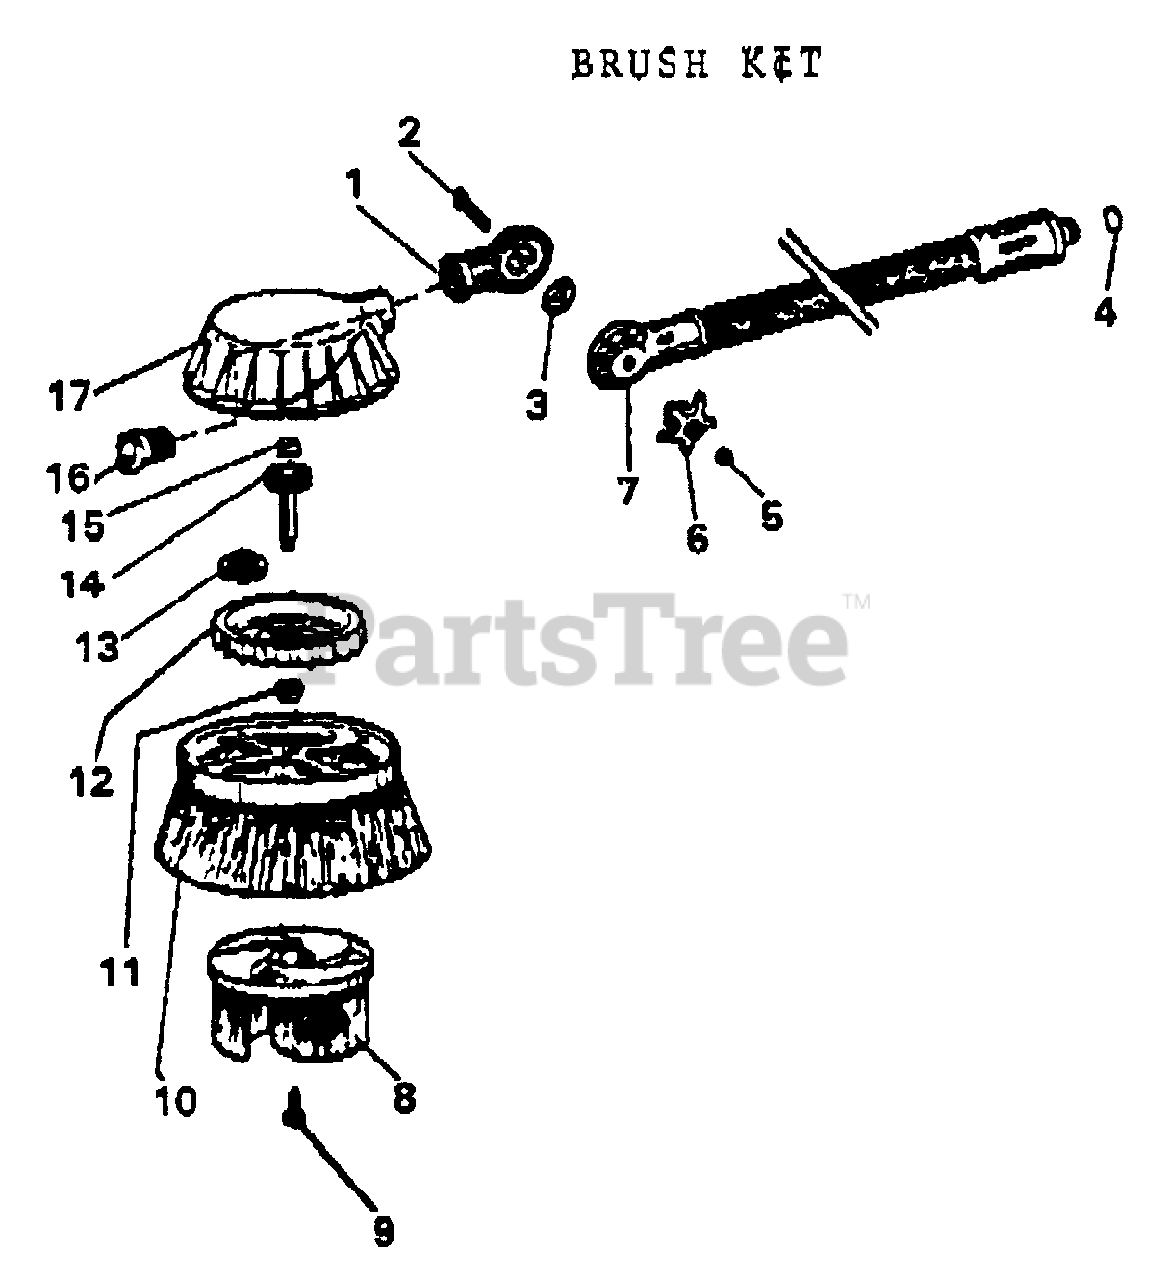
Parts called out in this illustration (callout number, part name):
1	CONNECTOR, ADJUSTABLE
2	SCREW M6×40
3	GASKET, CONNECTOR
4	O-RING
5	NUT - 6
6	KNOB, REGULATING
7	HAND GRIP, BRUSH
8	BRUSH, ROTATING
9	SCREW 6P×13
10	BRUSH, FIXED
11	BUSHING
12	TURBINE
13	GEAR
14	SHAFT, GEAR
15	BUSHING
16	NOZZLE, 3.85
17	COVER
